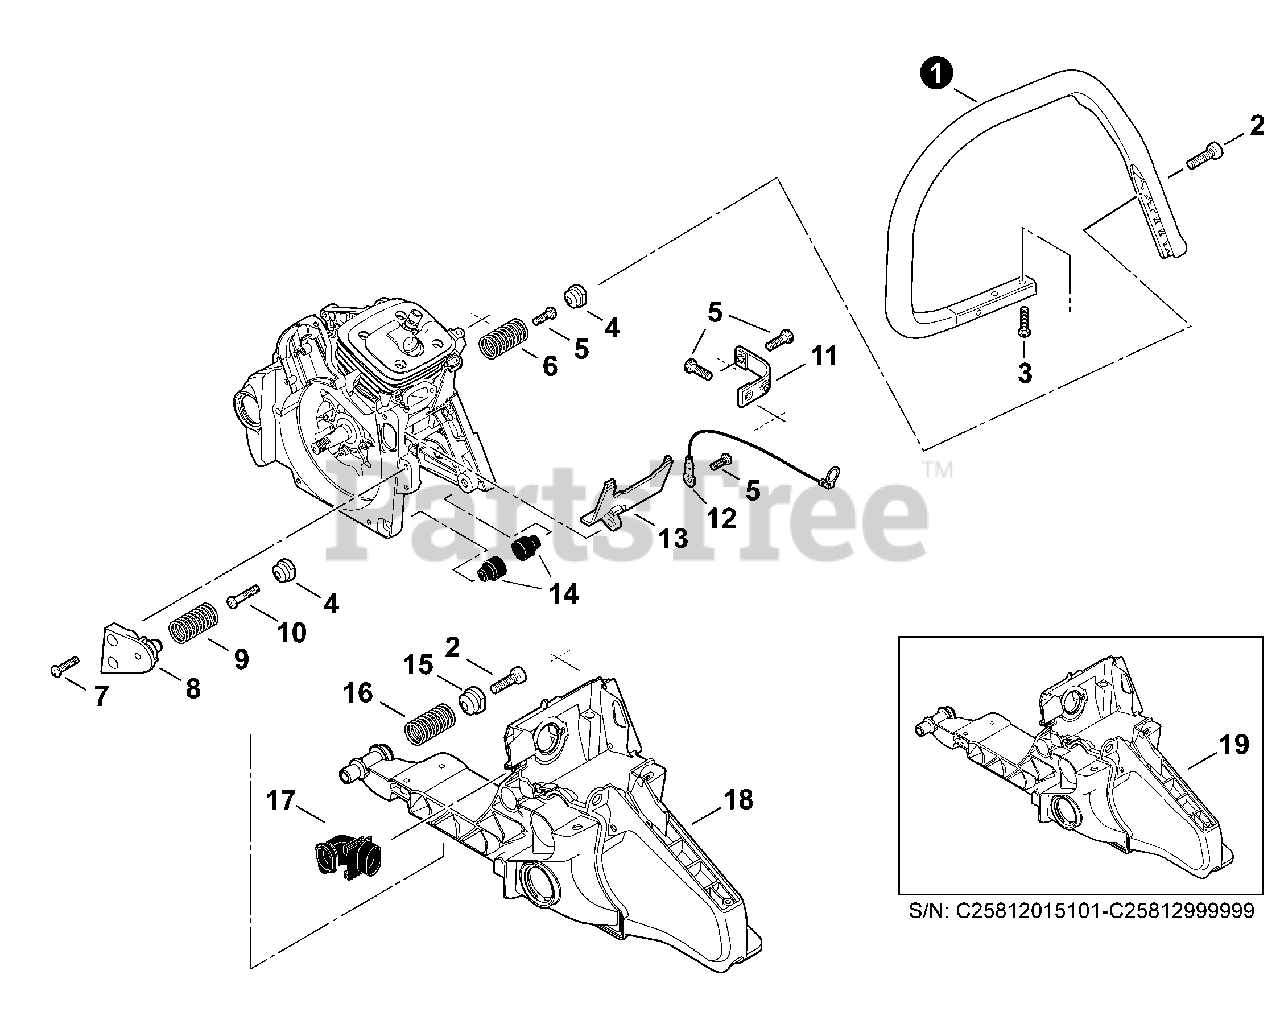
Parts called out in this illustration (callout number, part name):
1	HANDLE, FRONT
2	BOLT, TORX 6×20
3	BOLT, TORX 5×20
4	HOLDER, SPRING Ø14.4
5	BOLT, TORX 5×16
6	SPRING, COMPRESSION Ø17×38.4×2.6
7	BOLT, TORX 5×20
8	HOLDER, SPRING
9	SPRING, COMPRESSION Ø17×36.7×2.6
10	BOLT, TORX 5×25
11	STRAP, SAFETY
12	LEAD - GROUND L= 170
13	GUIDE, AIR
14	CUSHION
15	HOLDER, SPRING Ø17
16	SPRING, COMPRESSION Ø20×40×3.3
17	PIPE, AIR INTAKE
18	HANDLE, REAR
19	HANDLE, REAR
